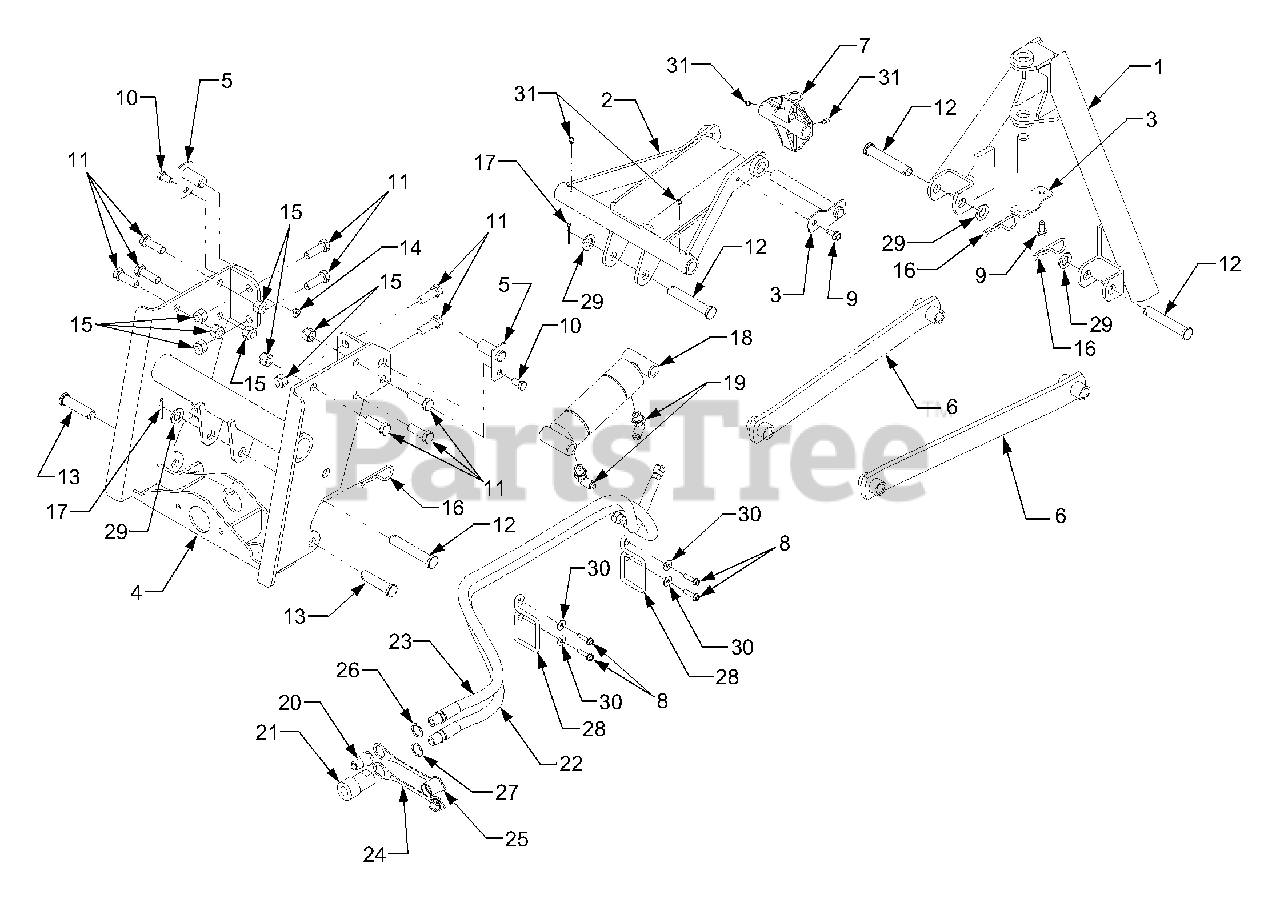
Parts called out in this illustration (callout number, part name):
1	Frame, Hitch A
2	Link, Top Pivot
3	Pin Assembly, Hitch Pivot
4	Brace Assembly, Front Hitch
5	Pin Assembly, Hitch Pivot
6	Arm, Front Hitch
7	Housing, Pivot
8	Screw, Hex Wash Hd Tapp. 1/4-20 x 1.0
9	Screw, Hex Wash Hd Tapp. 5/16-18 x .75
10	Screw, Hex Cap Lock 3/8-16 x .75 GR5
11	Screw, Hex Cap 1/2-13 x 1.50 GR5
12	Pin, Clevis, .625 x 3.45
13	Pin, Clevis, .625 x 2.313
14	Nut, Hex Insert Lock, 3/8-16 GR5
15	Nut, Hex Insert Lock, 1/2-13 GR8
16	Pin, Internal Cotter
17	Pin, Cotter, 1/8 x 1.25
18	Cylinder, Hitch Lift
19	Fitting, 90°.
20	Coupling, Hydraulic - Male
21	Coupling, Hydraulic - Female
22	Hose, Hydraulic, 1/4 ID x 42.0
23	Hose, Hydraulic, 1/4 ID x 46.0
24	Plug, Hydraulic Coupler - Male
25	Plug, Hydraulic Coupler - Female
26	Washer, Indicator - Green
27	Washer, Indicator - Blue
28	Rod, Hose Support
29	Washer, Flat, .635 x 1,125 x .09
30	Washer, Flat, .26 x .72 x .06
31	Fitting, Lube
